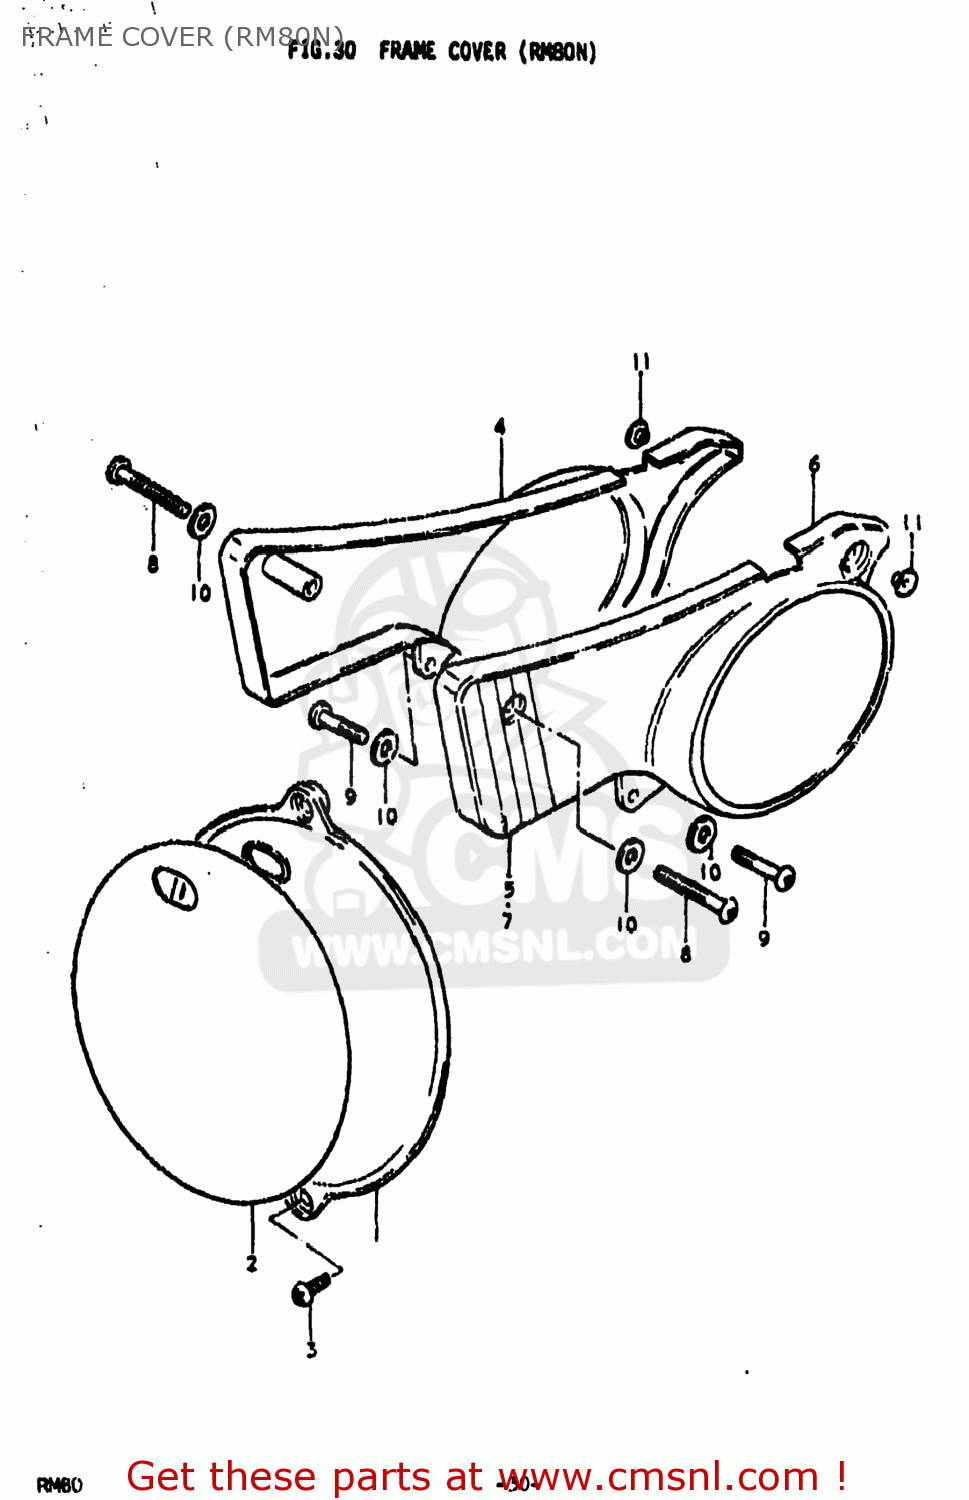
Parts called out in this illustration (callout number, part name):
1	PLATE,NUMBER,FRONT
2	EMBLEM,FRONT NUMBER PLATE
3	SCREW
4	COVER,FRAME,RIGHT
5	TAPE,FRAME COVER
6	COVER,FRAME,LEFT
7	TAPE,FRAME COVER
8	SCREW, NO.1
9	SCREW
10	WASHER
11	SPACER
